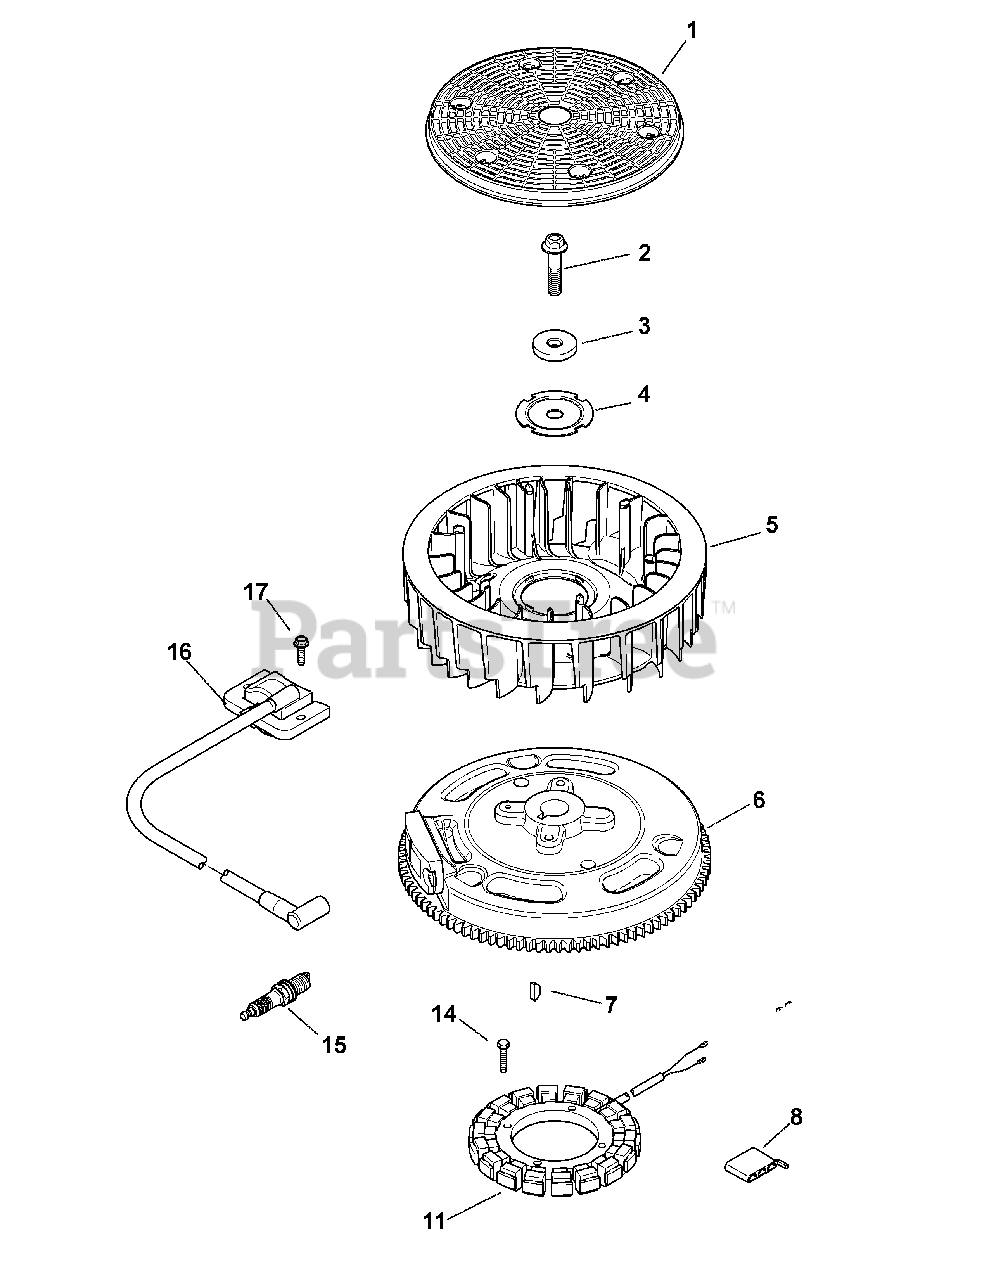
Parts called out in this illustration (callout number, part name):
2	Flg. Screw, M 10 X 1.5 X 45
3	Flat Washer, 13.32
4	Fan Mounting Plate
5	Fan
6	Flywheel Assembly
7	Key, 3.16 X 5.8
11	15 Amp Stator Kit
14	Thd. Frm. Screw, M5 X 0.8 X 25
15	Spark Plug
16	Module Ignition Kit
17	Flg. Thd. Frm. Screw, M5 X .8 X 20
